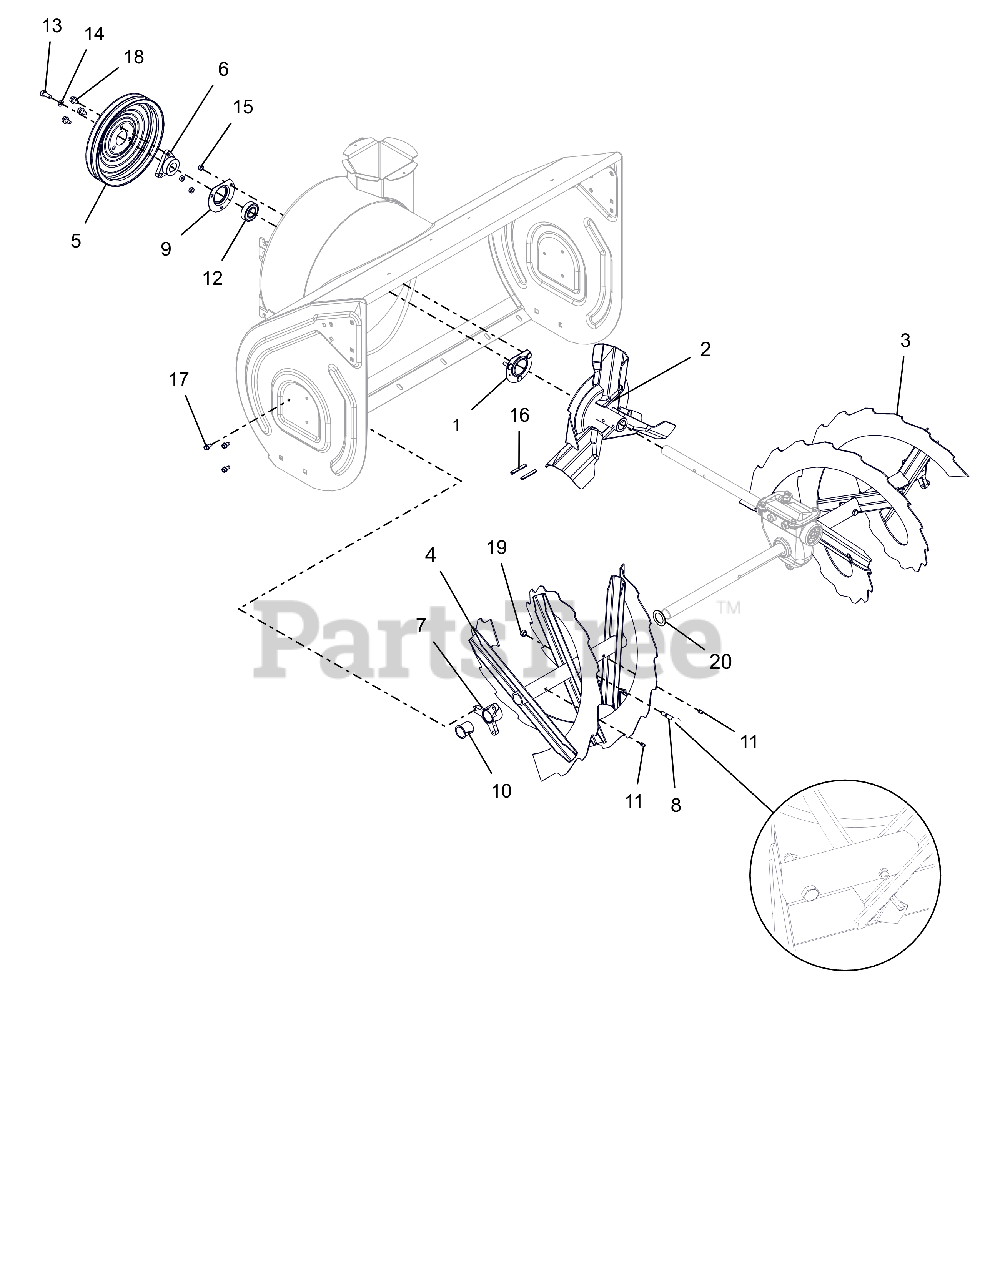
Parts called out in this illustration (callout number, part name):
1	BEARING FLANGE
2	IMPELLER, 3 BLADE-14"
3	RAKE, LH-32"(1 ID X 15.75 OD)
4	RAKE, RH-32"(1 ID X 15.75 OD)
5	PULLEY, SPIN FORM DUAL GROOVE
6	PULLEY HUB, D-BORE .87 PRO
7	BUSHING, RAKE SHAFT 1"
8	SHEAR BOLT SERVICE ASSEMBLY
9	BEARING FLANGE
10	BSHG-FLG SPLIT NYLINER 1.0" HP
11	ZERK,FITTING .25X.125 DRIVE IN
12	BRG-BALL .876X1.75X.50 RSTFP
13	BLT, HEX .31-24X.750 G5 ZCC
14	WSHR, LK-HVY .312X.097 ZCC
15	NUT,LK-CTR .25-20 GA ZCC
16	PIN-ROLL .250X1.75
17	SCR-TAP .25-20X.50 HWH ZCC
18	SCR,TAP .312-18X.50 HWH TR ZCC
19	NUT,LK-CTR .31-18 GA ZCC
20	WSHR, FLT 1.010X1.505X.062 ZCC
